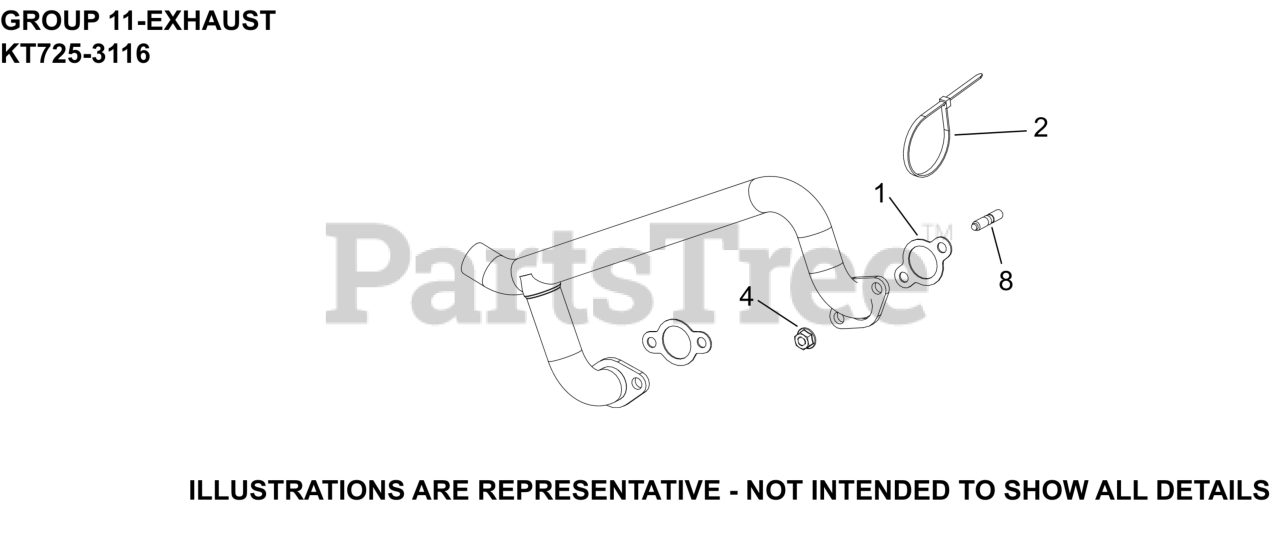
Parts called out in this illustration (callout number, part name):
1	GASKET, EXHAUST MANIFOLD
4	NUT, HEX FLANGE LOCK (M8)
8	STUD, METRIC EXHAUST
